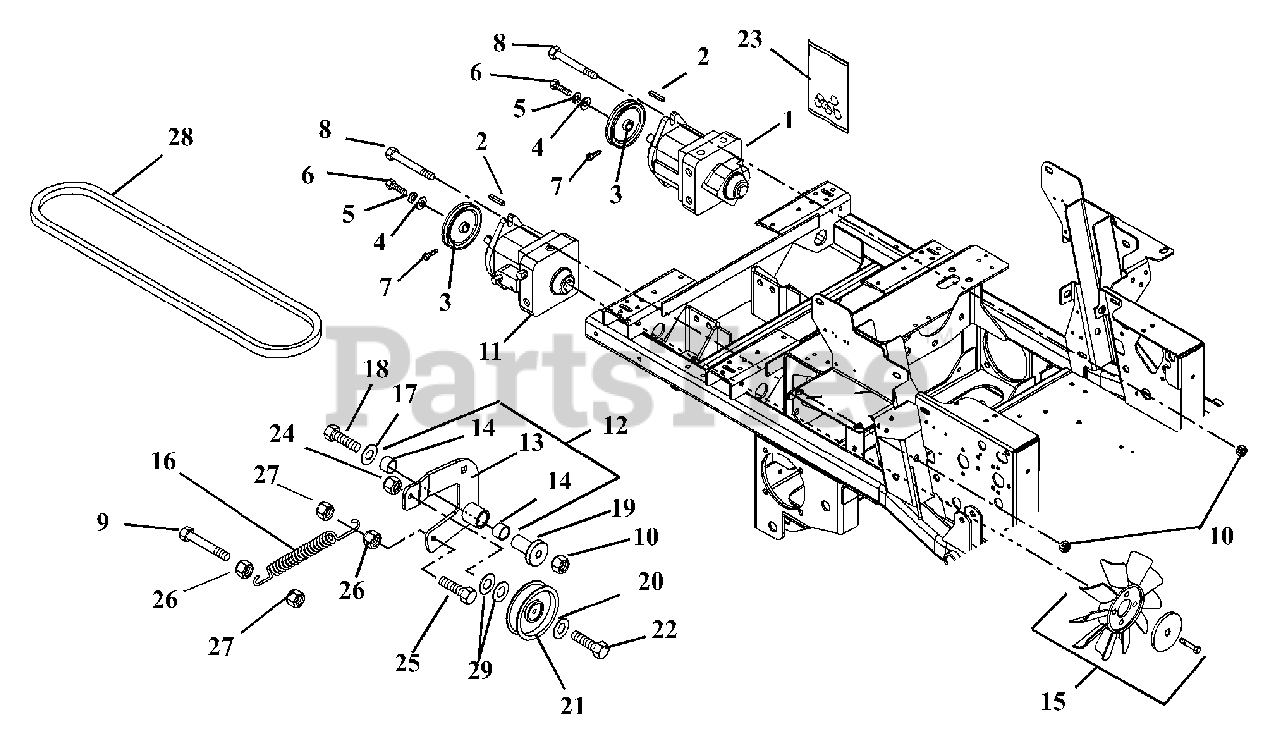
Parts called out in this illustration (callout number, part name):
1	PUMP - HYDRAULIC RTN W/AUX
2	KEY, SQ 5 X 5 X 30MM PLAIN
3	SHEAVE, POLY V .671 X 4.125
4	WASHER, PUMP .28X1.25X.50
5	@WSHR-LK .25X.062 REG YWZC
6	@BLT-HEX M6-1X16 YWZC
7	SCR-SKH .25-20 X .50 PH & OIL
8	@BLT-HEX .50-13X1.50 GR5 YWZC
9	@BLT-HEX .31-18X2.50 GR5 YWZC
10	@NUT-LK-TOP-FLG .50-13 YWZC
11	PUMP-HYD RTN THRU SHAFT F/FAN
12	ASSEMBLY, IDLER ARM
13	WMT, IDLER ARM
14	BRG, 1.00 X 1.12 X .75
15	FAN KIT, HYDROGEAR 70618
16	SG-TENS .135X.69X5.75 WLD 150
17	@WSHR-FL-STL.563X1.38X.109YWZC
18	@BLT-HEX .50-13X3.50 GR5 YWZC
19	BEARING, PEDESTAL
20	@WSHR-FL-STL.406X.812X.065 YWZ
21	IDLER, FLAT .377X4.0X.96W POLY
22	@BLT-HEX .38-16X2.00 GR5 YWZC
23	KIT, PUMP SEAL (BDP-21L)
24	@NUT-LK-TOP-FLG .38-16 YWZC
25	@BLT-HEX .31-18X1.25 GR5 YWZC
26	@NUT-HEX .31-18 YWZC
27	@NUT-LK-TOP-FLG .31-18 YWZC
28	POLY V-BELT, K-5 RIBS
29	WSHR-FL-STL .390X.75X.125 YWZC
